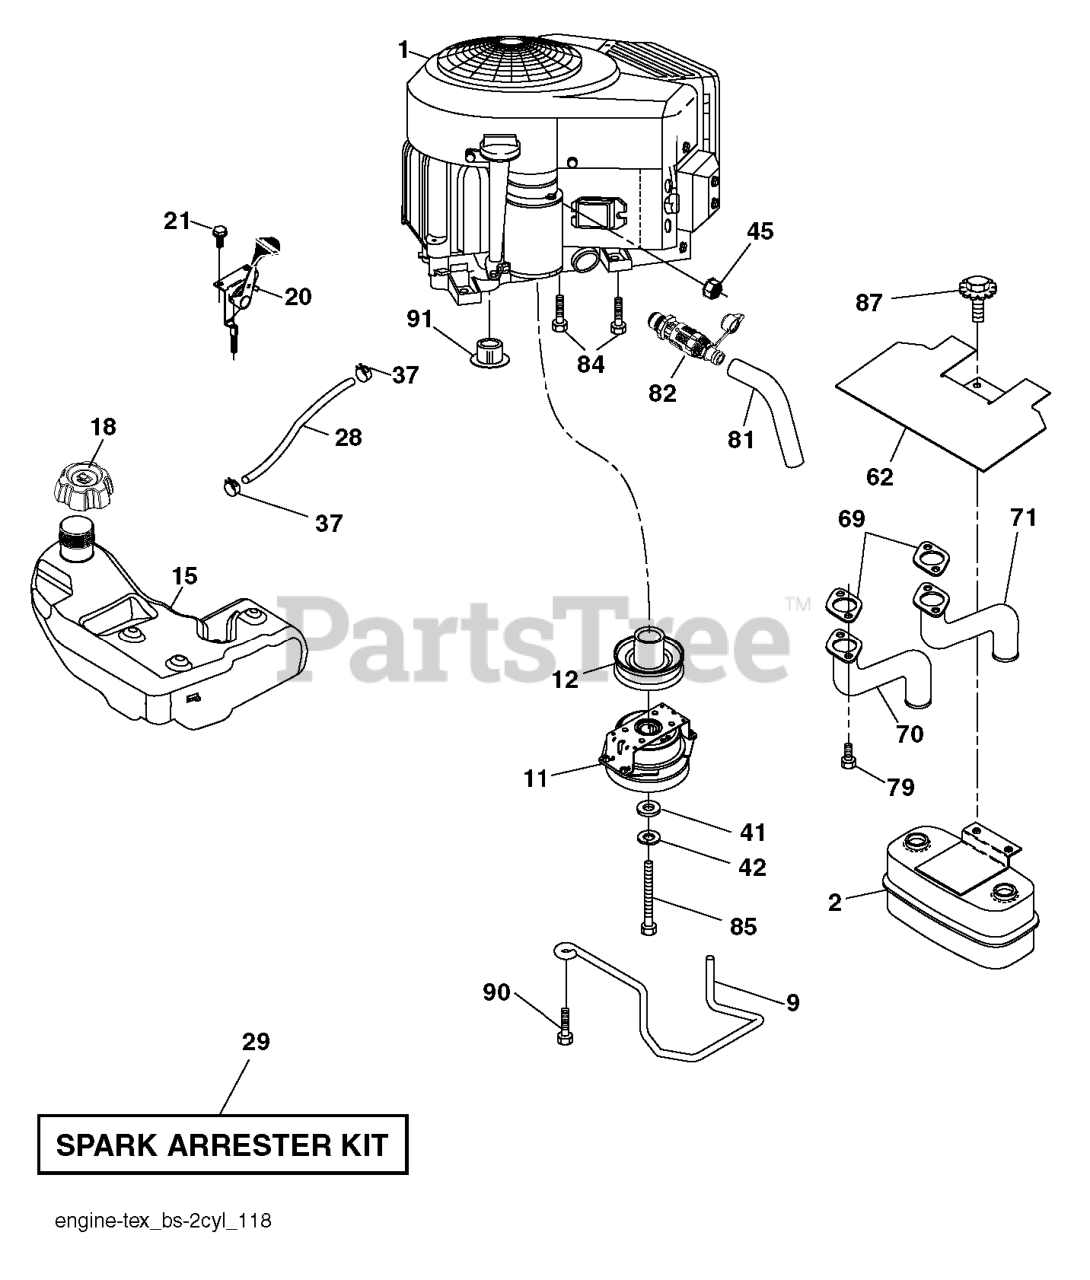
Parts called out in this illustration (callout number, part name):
2	MUFFLER.ASM.TWN.EXTNDED.DFLCTR
9	KEEPER.BELT.ENGINE.4.2
11	CLUTCH.ELECTRIC.LT.48"*
12	PULLEY.ENGINE.TUFFTORQ
15	RP_TANK.ASSY.3.GAL.EPA
18	CAP.ASM.FL.RITCH.3"E10.SYM.498
20	CONTROL.TH/CK.COBRA.B&S.TWN.BK
21	SCREW.#10 X 0.750.BOS
28	LINE.FUEL.64"REAR.EMIS
29	KIT.SPARK ARRESTOR 794945 B&S
37	HOSE CLAMP
42	LOCKWASHER
45	NUT
62	SHIELD.HEAT.MUFFLER
69	GASKET.MUFFLER
70	RP.EXHAUST.TUBE.LH.BS/TWIN
71	EXHAUST.TUBE.RH.BS/TWIN
79	SCREW.SOCKET.HEAD.5/16-18
81	TUBE, DRAIN OIL ASM.
82	PLUG DRAIN OIL EASY
84	SCREW.3/8-16
85	BOLT HEX 7/16-20X4-1/4"
87	BOLT.5/16-18UNCX3/4 W/SEMS.BLK
90	SCREW 3/8-16X1
91	BUSHING.1.375OD
